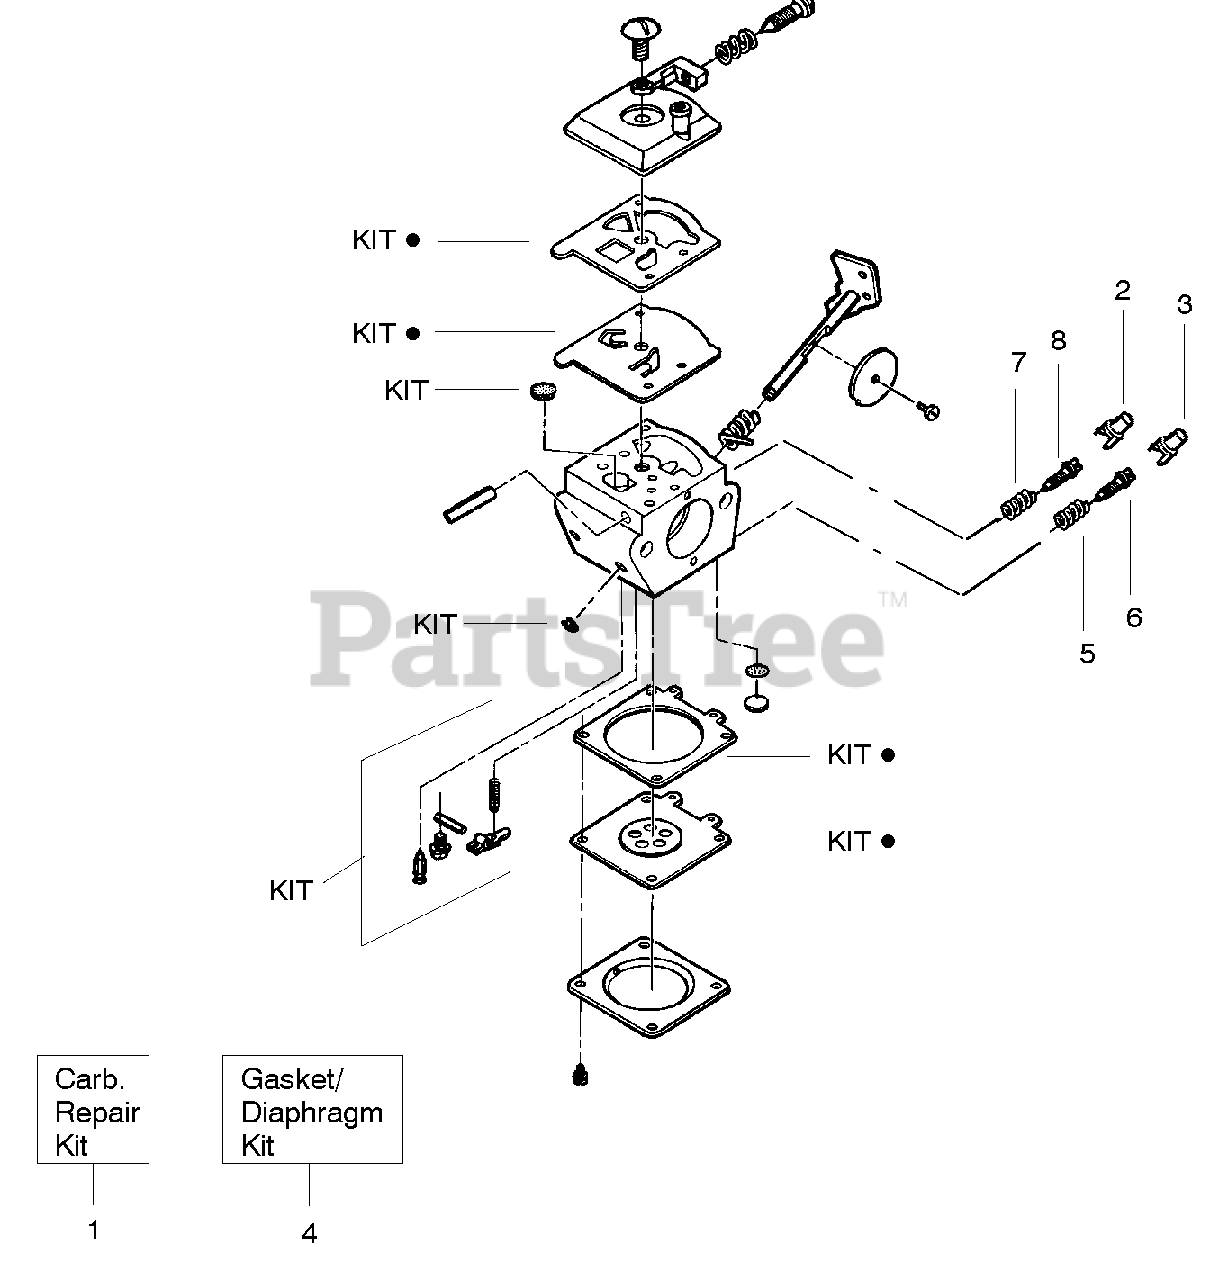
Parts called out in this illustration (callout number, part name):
1	Carburetor Repair Kit (KIT= Indicates Contents)
2	Limiter Cap (High-Red)
3	Limiter Cap (Low-Blue)
4	Gasket/Diaphragm Kit
5	Needle Spring-Low Speed
6	Needle-Low Speed
7	Needle Spring-High Speed
8	Needle-High Speed
